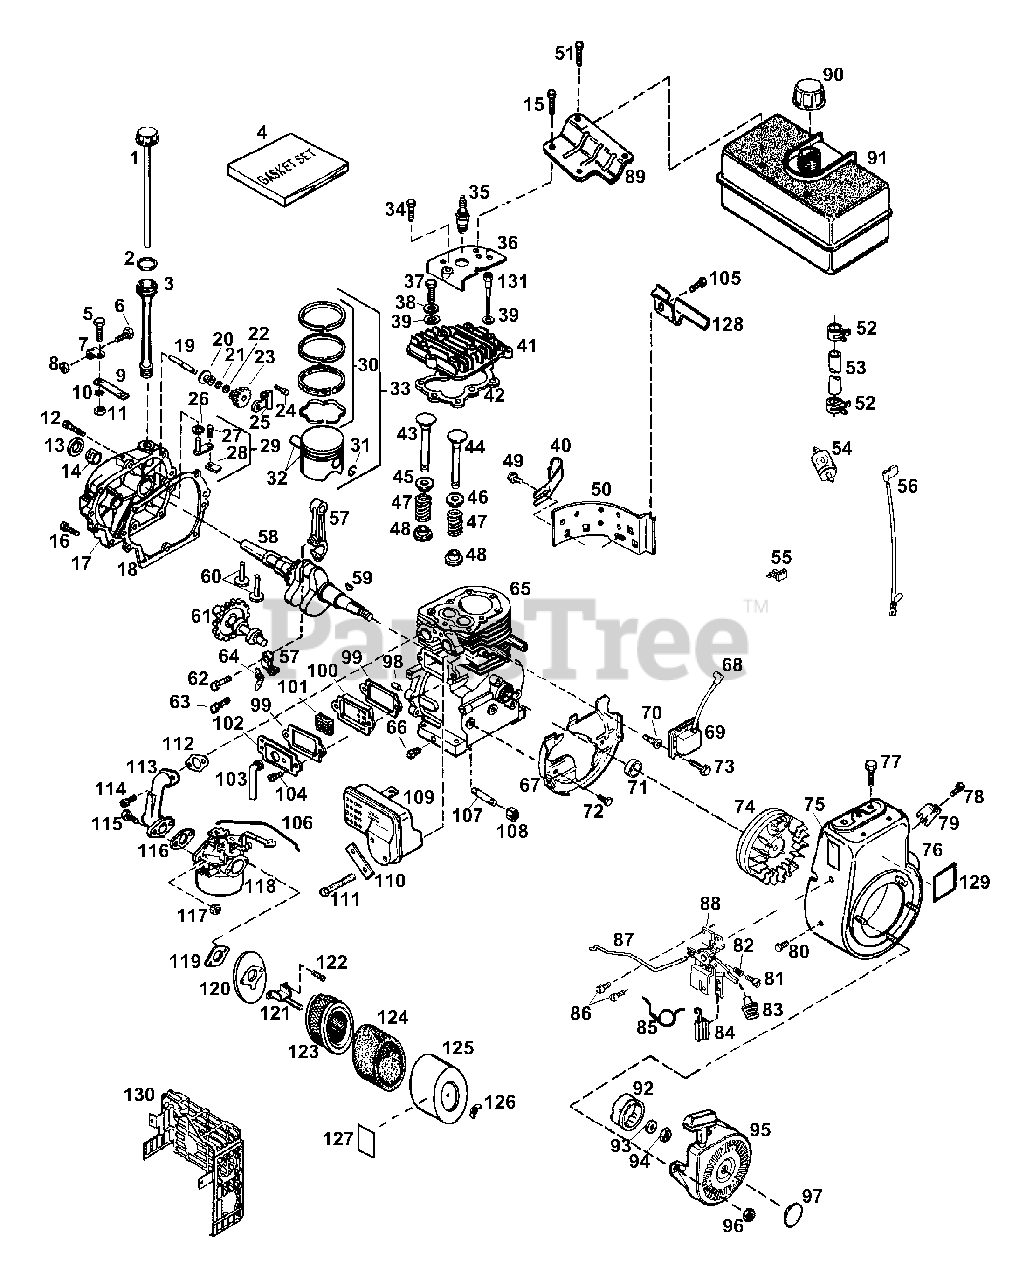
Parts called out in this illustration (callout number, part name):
3	Oil Fill Tube
4	Gasket Set
5	Screw, 8-32 x 5/16"
6	Screw, 10-32 x 3/4"
7	Governor Lever Clamp
8	Lock Nut, 10-32
9	Governor Lever
10	Lock Washer
11	Lock Nut, 8-32
12	Screw, 1/4-20 x 1-3/16"
14	Crankshaft Bushing
15	Screw, 1/4-20 x 5/8"
16	Screw, 1/4-20 x 1-11/16"
17	Cylinder Cover
18	Cylinder Cover Gasket
19	Governor Shaft
20	Governor Spool
22	Retaining Ring
23	Governor Gear Assy.
24	Screw, 10-24 x 1/2"
25	Governor Gear Bracket
26	Retaining Ring
27	Screw, 6-40 x 5/16"
28	Governor Yoke
29	Governor Rod
30	Ring Set (Standard)
31	Piston Pin Retaining Ring
32	Piston & Pin Assy (Standard)
33	Piston, Pin & Ring Set (Standard)
34	Screw, 1/4-20 x 5/8"
35	Resistor Spark Plug (J8C/356)
36	Cylinder Head Cover
37	Screw, 5/16-18 x 2"
38	Belleville Washer
40	Fill Tube Clip
41	Cylinder Head
42	Cylinder Head Gasket
43	Intake Valve (Std.)
44	Exhaust Valve (Std.)
45	Valve Spring Cap
46	Valve Spring Cap
47	Valve Spring
48	Valve Spring Keeper
49	Screw, 10-24 x 1/2"
50	Blower Housing Extension
51	Screw, 1/4-15 x 3/4"
52	Fuel Line Clamp
53	Fuel Line
54	Fuel Filter
55	Wire Clip
56	Ground Wire
57	Connecting Rod Assy
58	Crankshaft
59	Flywheel Key
60	Valve Lifter
61	Camshaft (MCR)
62	Connecting Rod Bolt
63	Connecting Rod Bolt
64	Oil Dipper
65	Cylinder
66	Oil Drain Plug
67	Blower Housing Baffle
68	Spark Plug Cover
69	Solid State Ignition
70	Solid State Mounting Stud
72	Screw, 1/4-20 x 5/8"
73	Screw, Torx T-15, 10-24 x 15/16"
75	Instructional Decal
76	Blower Housing
77	Screw, 5/16-18 x 3/4"
78	Screw, 8-32 x 3/8"
79	Starter Bubble Cover
80	Screw, Torx T-40, 5/16-24 x 21/32"
81	Screw, 5-40 x 7/16"
82	Compression Spring
83	Control Knob
85	Speed Control Spring
86	Screw, 10-32 x 1/2"
87	Governor Link
88	Control Bracket
89	Fuel Tank Bracket
90	Fuel Cap
91	Fuel Tank
92	Starter Cup
93	Lock Washer
94	Flywheel Nut
95	Rewind Starter
96	Nut & Lock Washer, 1/4-28
97	Starter Decal
98	Dowel Pin
99	Valve Cover Gasket
100	Breather Body
101	Breather Element
102	Valve Cover
103	Breather Tube
104	Screw, 10-24 x 1/2"
105	Screw, 1/4-20 x 5/8"
106	Throttle Link
107	Oil Drain Extension
108	Extension Cap
110	Locking Plate
111	Screw, 5/16-18 x 3-3/16"
112	Intake Pipe Gasket
113	Intake Pipe
114	Screw, Torx T-30, 5/16-18 x 1-1/8"
115	Screw, 1/4-28 x 1"
116	Carburetor To Intake Pipe Gasket
117	Nut & Lock Washer, 1/4-28
118	Carburetor
119	Air Cleaner Gasket
120	Air Cleaner Body
121	Air Cleaner Bracket
122	Screw, 10-32 x 1/2"
123	Air Cleaner Filter
124	Air Cleaner Filter
125	Air Cleaner Cover
126	Wing Nut, 1/4-20
127	Oil Instruction Decal
128	Fuel Tank Bracket
129	Throttle Decal
130	Heat Shield
131	Screw, 5/16-18 x 1-3/4"
